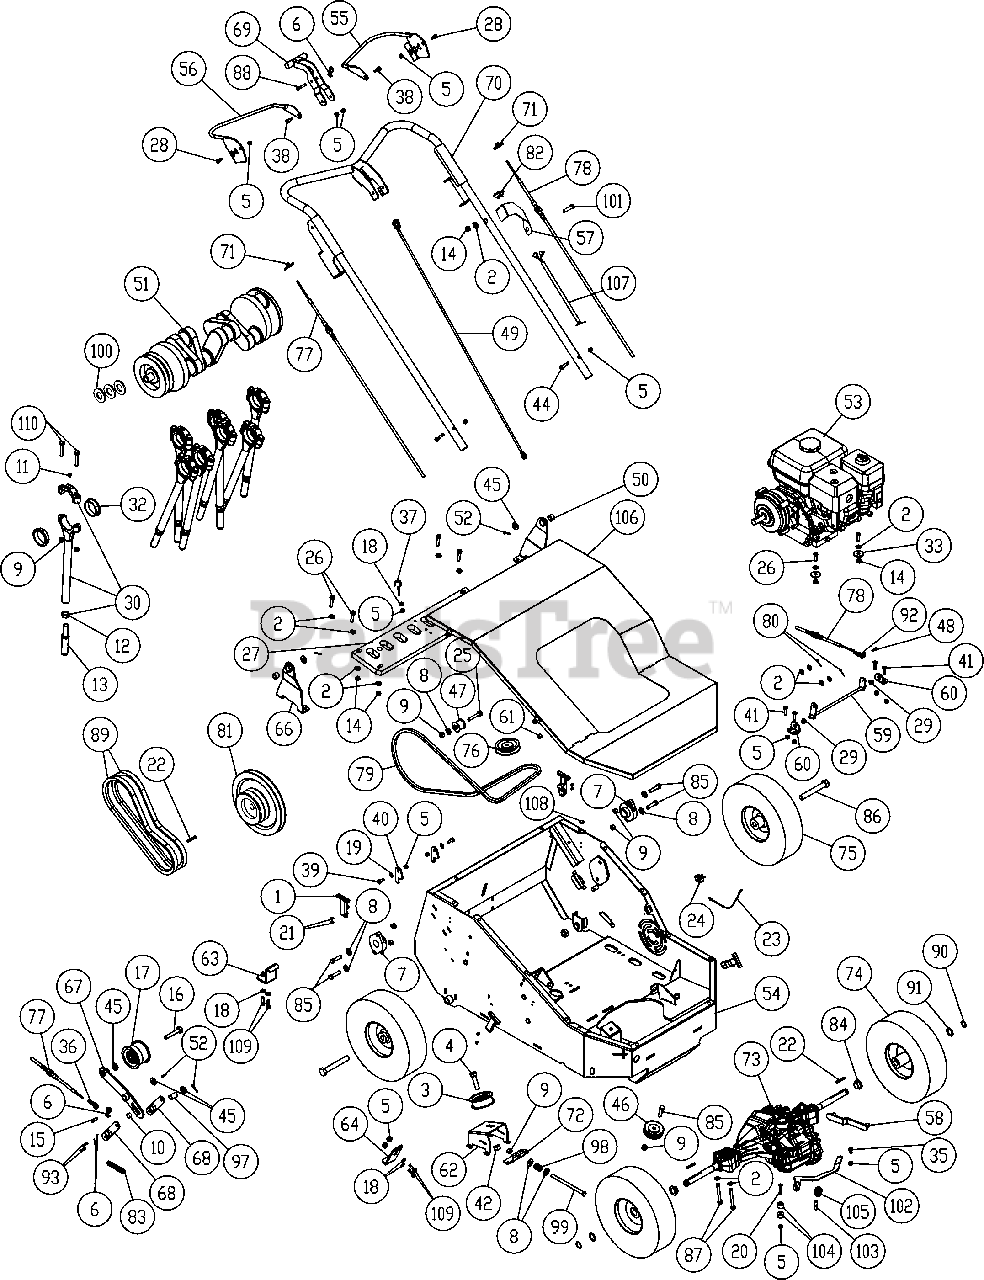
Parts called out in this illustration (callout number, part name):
1	RUBBER LATCH KIT
2	WASHER 5/16" FLAT
3	IDLER PULLEY 2.75" DIA
4	SCREWCAP 3/8"-16 X 1 1/2" HCS ZP
5	NUTLOCK 1/4"-20
6	RUE RING 1/4"
7	CARTRIDGE BEARING 1"
8	WASHER 3/8" FLAT
9	NUTLOCK 3/8"-16
10	ROLLER 0.5 OD X 0.25 ID X 0.313
11	GREASE FITTING 1/4"-28
12	NUT JAM 5/8"-11 UNC
13	TINE 5/8"
14	NUTLOCK 5/16"-18 HEX ZP
15	CLEVIS PIN 1/4" X 3/4"
16	SCREWCAP 1/2"-13 X 2 1/2" HCS ZP
17	PULLEY IDLER 2.75 X 1.50"
18	WASHER 1/4" FLAT
19	BELLEVILLE WASHER 1/4"
20	BUTTON HEAD SCREW 1/4"-20 X 1 1/2"
21	STAINLESS RIVET 1/8" X 1/4"
22	KEY 3/16" X 2 1/8"
23	WIRE HARNES PL HOOD SWITCH
24	SWITCH INTERLOCK
25	SCREWCAP 3/8"-16 X 2" HCS ZP
26	SCREWCAP 5/16"-18 X 1 3/4" HCS ZP
27	8 TINE RETRACTOR PLATE
28	SHOULDER BOLT 5/16" X 1/4"
29	FLANGE BUSHING 5/16" ID X 7/16" OD
30	KIT KEYED TINE ROD AND CAP
32	JOURNAL BEARING 2"
33	FENDER WASHER 5/16"
35	SCREWCAP 1/4"-20 X 1" HCS ZP
36	SPHERICAL ROD END 10-32 UNF
37	BOLT EYE 1/4"-20 X 2" OPEN END
38	SHOULDER BOLT 5/16" X 3/8"
39	SCREWCAP 1/4"-20 X 3/4" HCS ZP
40	TOWBAR BRACKET KEEPER
41	SCREWCAP 1/4"-20 X 1" HCS ZP
42	NUT LOCK 1/2"-13 UNC
44	SCREWCAP 1/4"-20 X 1 3/4" HCS ZP
45	WASHER 1/2" FLAT
46	PULLEY 3V GROOVE IDLER
47	PULLEY IDLER 1.13" OD X 3/8" BORE
48	PIN CLEVIS 3/16" X 3/4" ZP
49	CABLE RETRACTOR PLATE
50	BUSHING 1/2" ID X 3/4" OD X 1/2"
51	8 TINE CRANKSHAFT
52	COTTER PIN 1/8" X 1"
53	GX200 HONDA ENGINE W/GEAR BOX
54	PL855 FRAME
55	THROTTLE HAND LEVER
56	CLUTCH HAND LEVER
57	BRACKET MOUNT SWITCH
58	THROTTLE LINK
59	THROTTLE BAR
60	THROTTLE LINK TAB
61	PREHARD ROLLER
62	TENSION IDLER MOUNT BRACKET
63	BRACKET BELT FINGER LOWER PL25
64	BRACKET BELT FINGER UPPER PL25
66	RETRACTOR PLATE ARM
67	ARM IDLER W/BUSHING PL2500SPH
68	CLUTCH CAM ARM
69	HANDLE RETRACTOR WA PL25SP
70	HANDLE WA PL25SP 12 GA
71	CABLE ADJUSTMENT SPOOL
72	TENSIONER CROSS BAR
73	DUAL SHAFT TRANSAXLE
74	WHEEL 12" W/ 3/4" KEYED HUB
75	WHEEL 12" W/ 5/8" BEARING HUB
76	TRANSAXLE PULLEY 3.25 X 1/2" SPLINE
77	PUSH-PULL CABLE 55"
78	PUSH-PULL CABLE 69"
80	COTTER PIN 3/32 X 3/4"
81	PULLEY ENGINE PL2500SP
82	SWITCH LKG RKR
83	EXTENSION SPRING 1/2" X 3"-5"
84	FLANGE BUSHING 7/8" OD X 3/4" ID
85	SCREWCAP 3/8"-16 X 1 1/2" HCS ZP
86	SCREWCAP 5/8"-11 X 4 1/2" HCS ZP
87	SCREWCAP 5/16"-18 X 2 3/4" HCS ZP
88	CLEVIS PIN 1/4" X 1 3/8"
89	COGGED V-BELT B 35"
90	RING RETAINING "E" 3/4"
91	WASHER .765" ID X 1.25" OD X .06"
92	YOKE 10-32 UNF W/CLEVIS PIN
93	CLEVIS PIN 3/16" X 3/4"
97	BUSHING 1/2" ID X 5/8" OD X 1"
98	DIE SPRING 3/4" OD X 1.5"
99	SCREWCAP 3/8"-16 X 6" HEX TAP BOLT GR 5 ZP
100	MACHINERY BUSHING 1" X 1 1/2" X 14 GA
101	SCREWCAP 5/16"-18 X 1 1/2" GR 5 HCS ZP
102	TRANSAXLE DISENGAGE LEVER
103	DISENGAGE LOCK
104	DISENGAGE ROLLER
105	COMPRESSION SPRING 0.72 OD, 2-6"
106	COVER WA PL25SP
107	WIRE HARNESS SC
108	RUBBER BUMPER PUSH IN
109	SCREWCAP 1/4"-20 X 3/4" GR 5 HCS ZP
110	SHCS 3/8"-16 X 2 BLK OX
